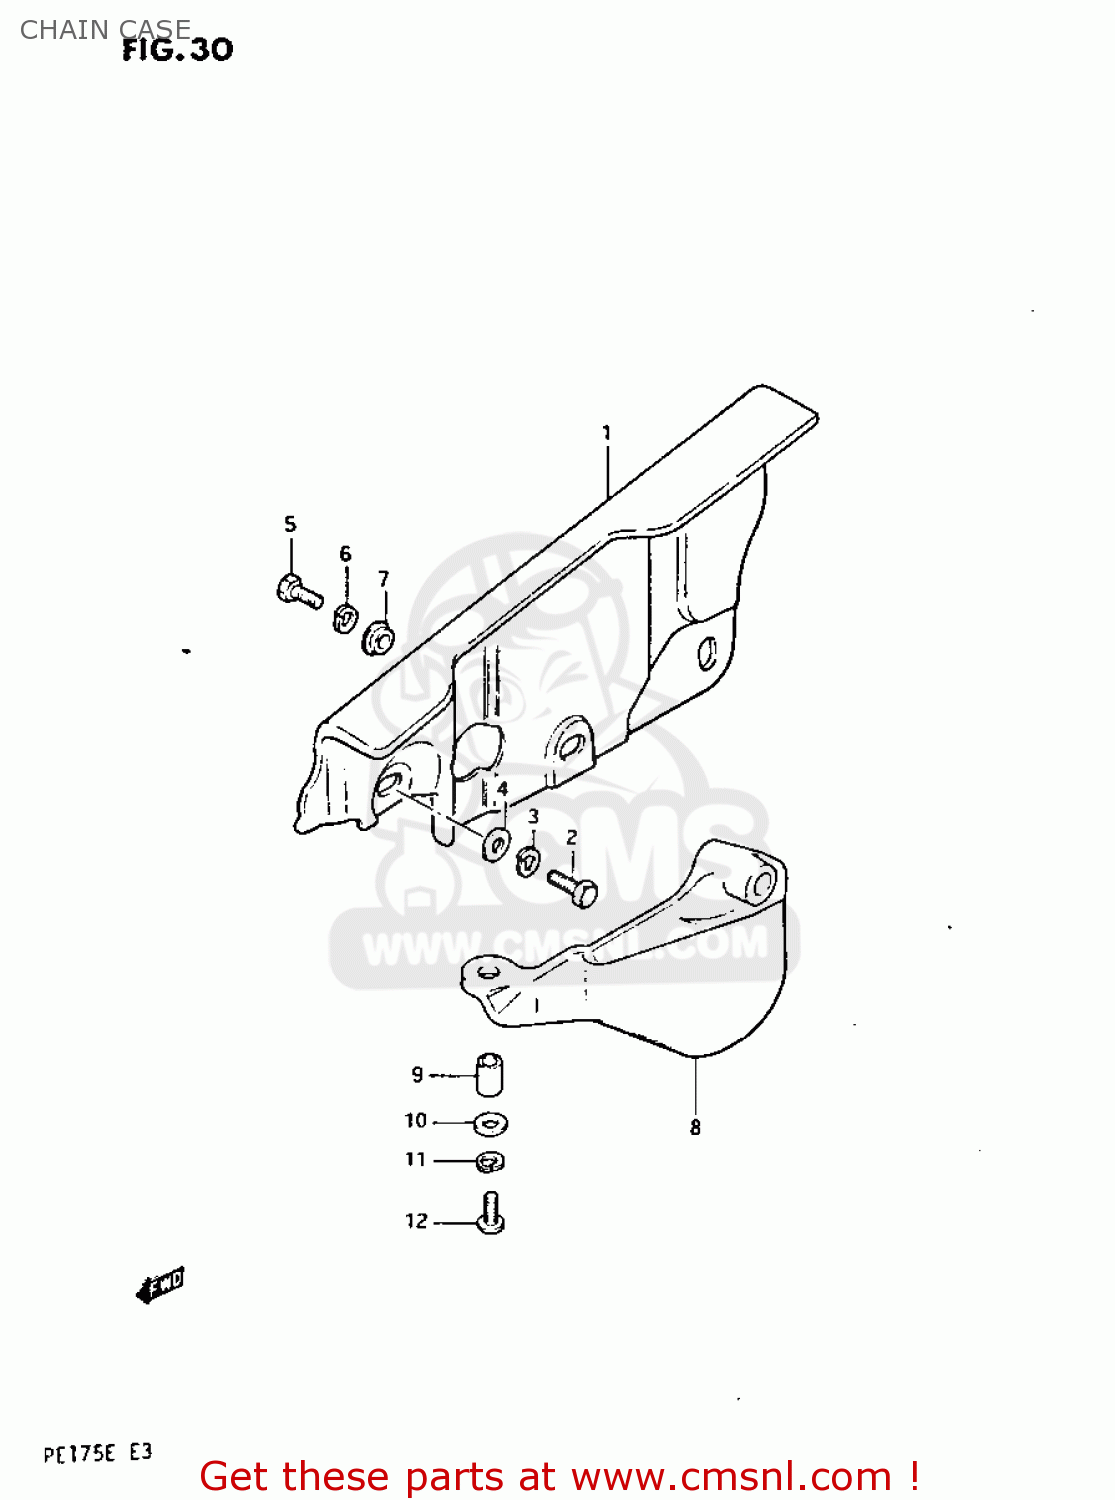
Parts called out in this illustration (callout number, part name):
1	CASE,CHAIN
2	BOLT
3	WASHER,LOCK
4	WASHER(6.5X18X1)
5	BOLT
6	WASHER,LOCK
7	WASHER
8	RUBBER,CHAIN CASE,LOWER
9	SPACER (6.1X8X5.2)
10	WASHER(6.5X18X1)
11	WASHER,LOCK
12	SCREW 6X12
